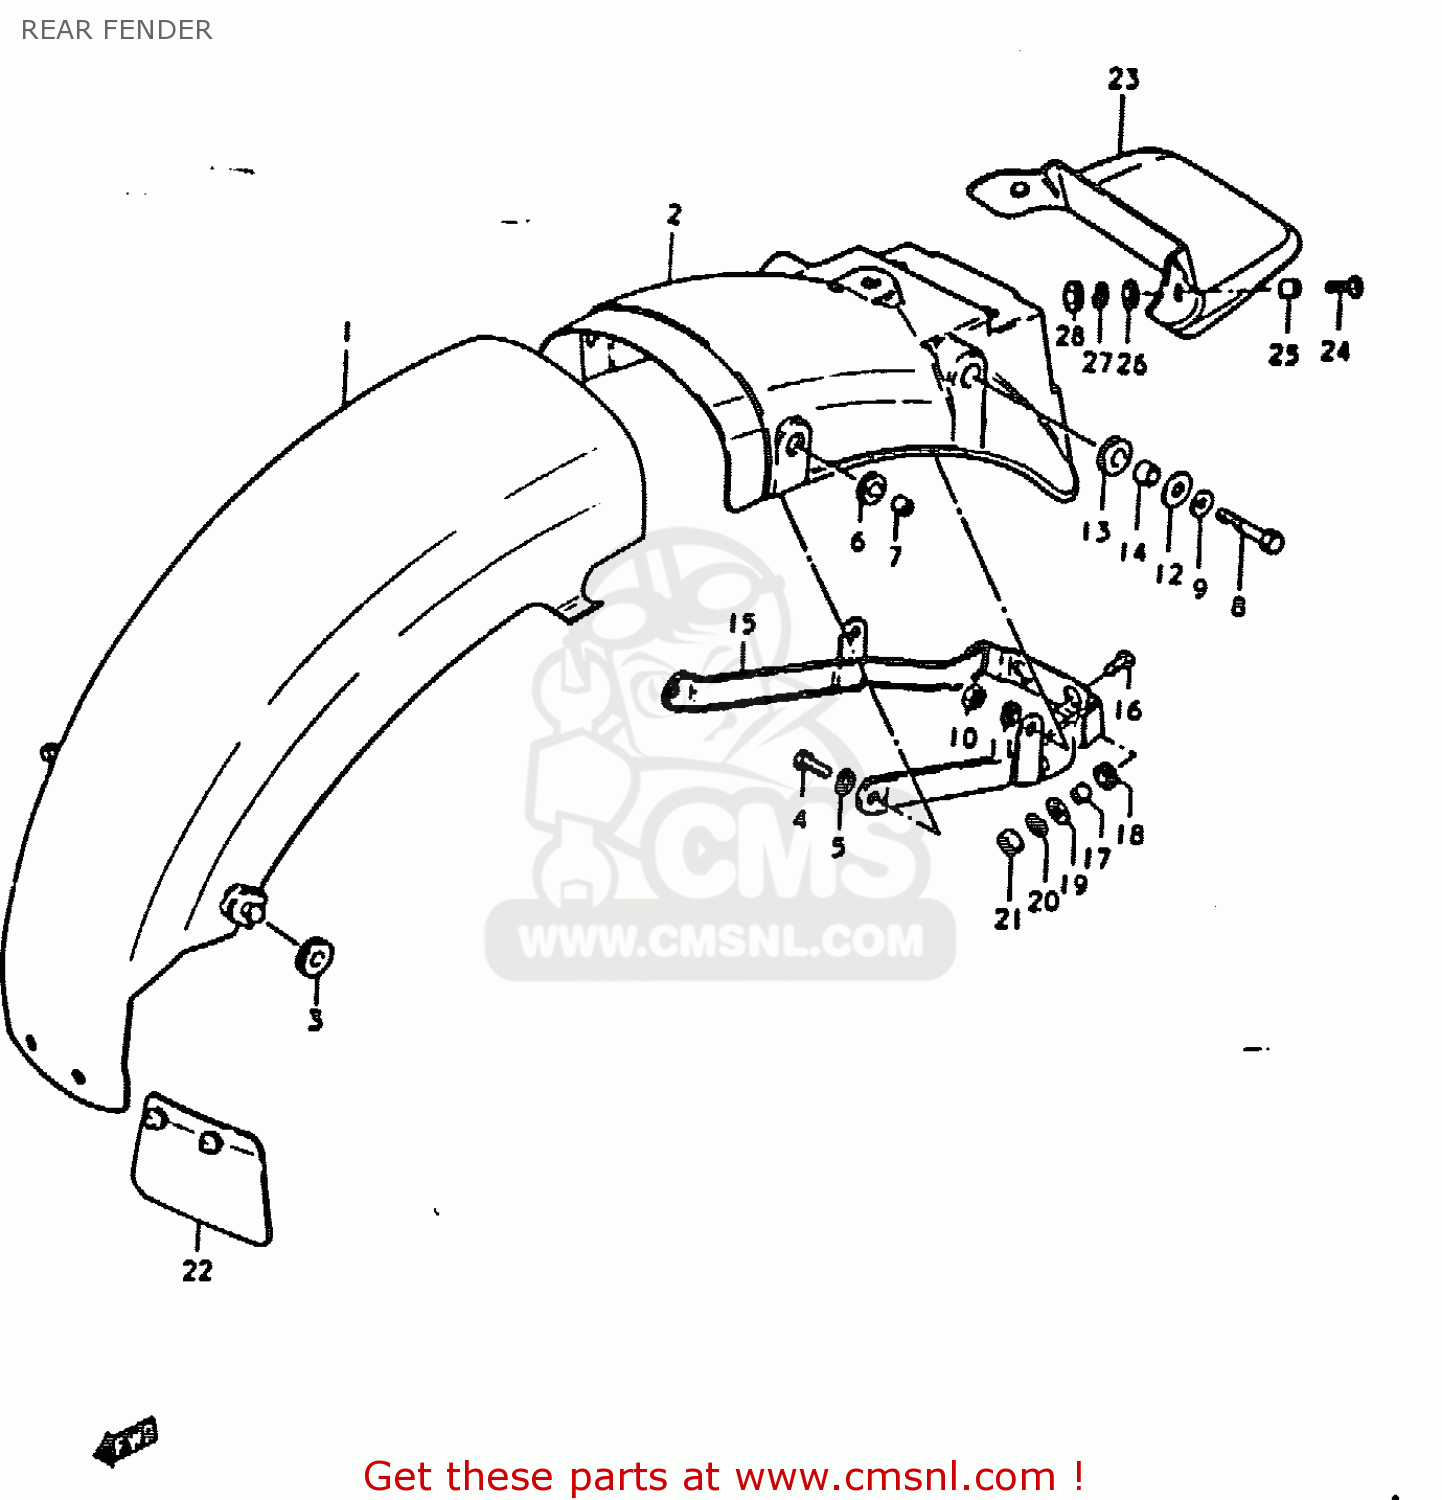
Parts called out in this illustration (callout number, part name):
1	FENDER,REAR
2	BODY,RR FENDER RR
3	CUSHION
4	BOLT
5	LOCK WASHER
6	CUSHION
7	SPACER(6.1X9X7.5)
8	BOLT
9	WASHER
10	NUT
11	LOCK WASHER
12	WASHER(8.5X26X1.2)
13	CUSHION
14	SPACER (8.2X12X7.5)
15	REINFORCEMENT,REAR FENDER
16	SCREW
17	SPACER (6.1X9X9)
18	CUSHION
19	WASHER(6,5X22X1.6)
20	LOCK WASHER
21	NUT
22	GUIDE,RR FENDER MUD
23	EXTENSION,REAR FENDER
24	SCREW (6X15)
25	SPACER(6.2X8.3X5.7)
26	WASHER(6.5X18X1)
27	LOCK WASHER
28	NUT
